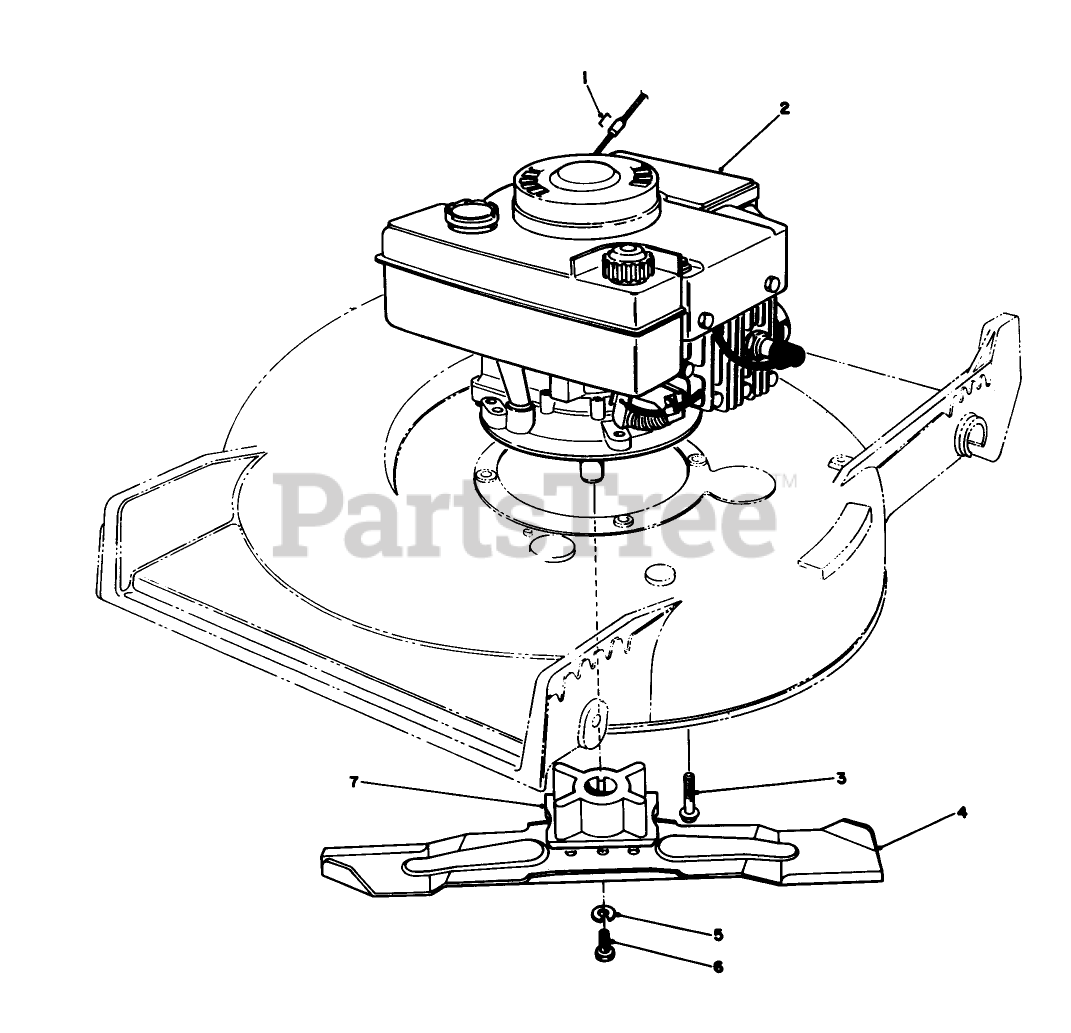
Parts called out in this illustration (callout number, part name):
1	Staple
2	Engine
3	3/8-16 X 2 CAPSCREW
5	WASHER-LOCK
6	SCREW-BLADE
7	BLADE RETAINER
